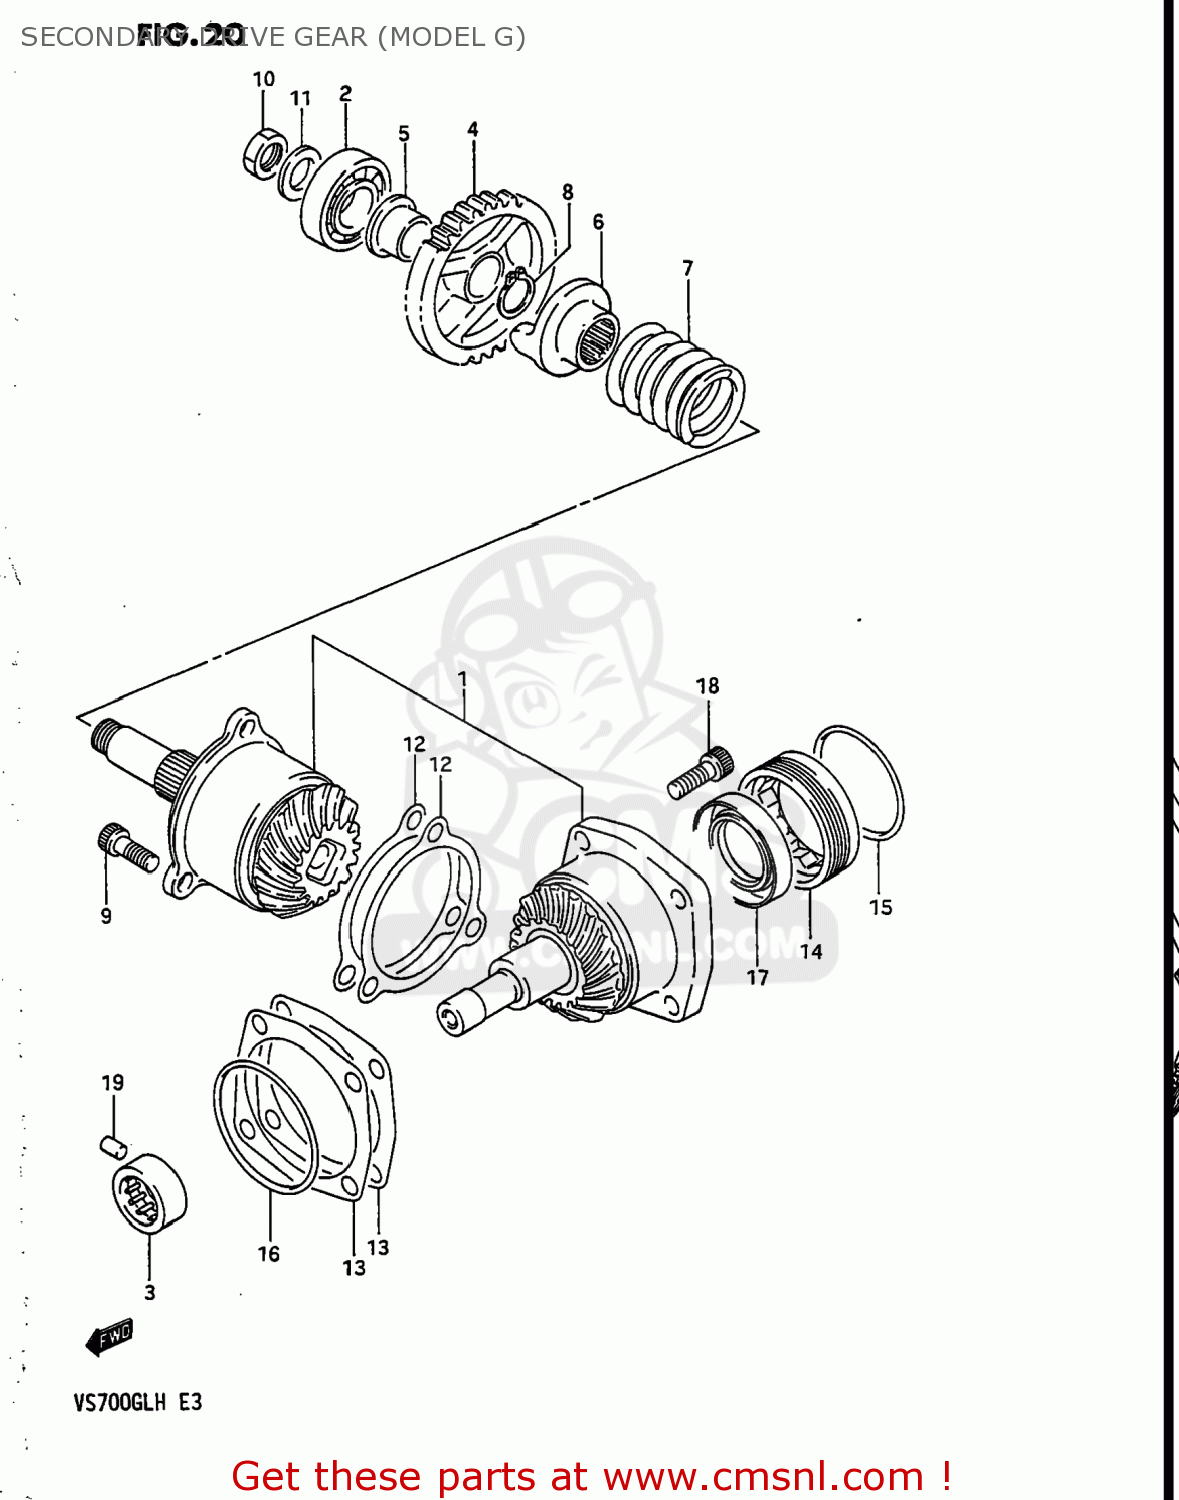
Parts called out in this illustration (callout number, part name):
1	GEAR,SECONDARY & HOUSING
2	BEARING(20X52X15)
3	BEARING(20X34X16)
4	GEAR,REDUCTION DRIVEN(NT:30)
5	BUSH,REDUCTION DRIVEN GEAR
6	DOG,OUTPUT CAM
7	SPRING
8	CIRCLIP,21MM
9	BOLT
10	NUT
11	WASHER(16X29X4)
12	SHIM,SECONDARY DRIVE
13	SHIM,SECONDARY DRIVEN HOUSING
14	STOPPER,SECONDARY DRIVEN BEARING
15	O RING(D:1.9,ID:61.6)
16	O RING(D:2.1,ID:66.2)
17	SEAL,OIL(38X54X6)
18	BOLT
19	PIN
